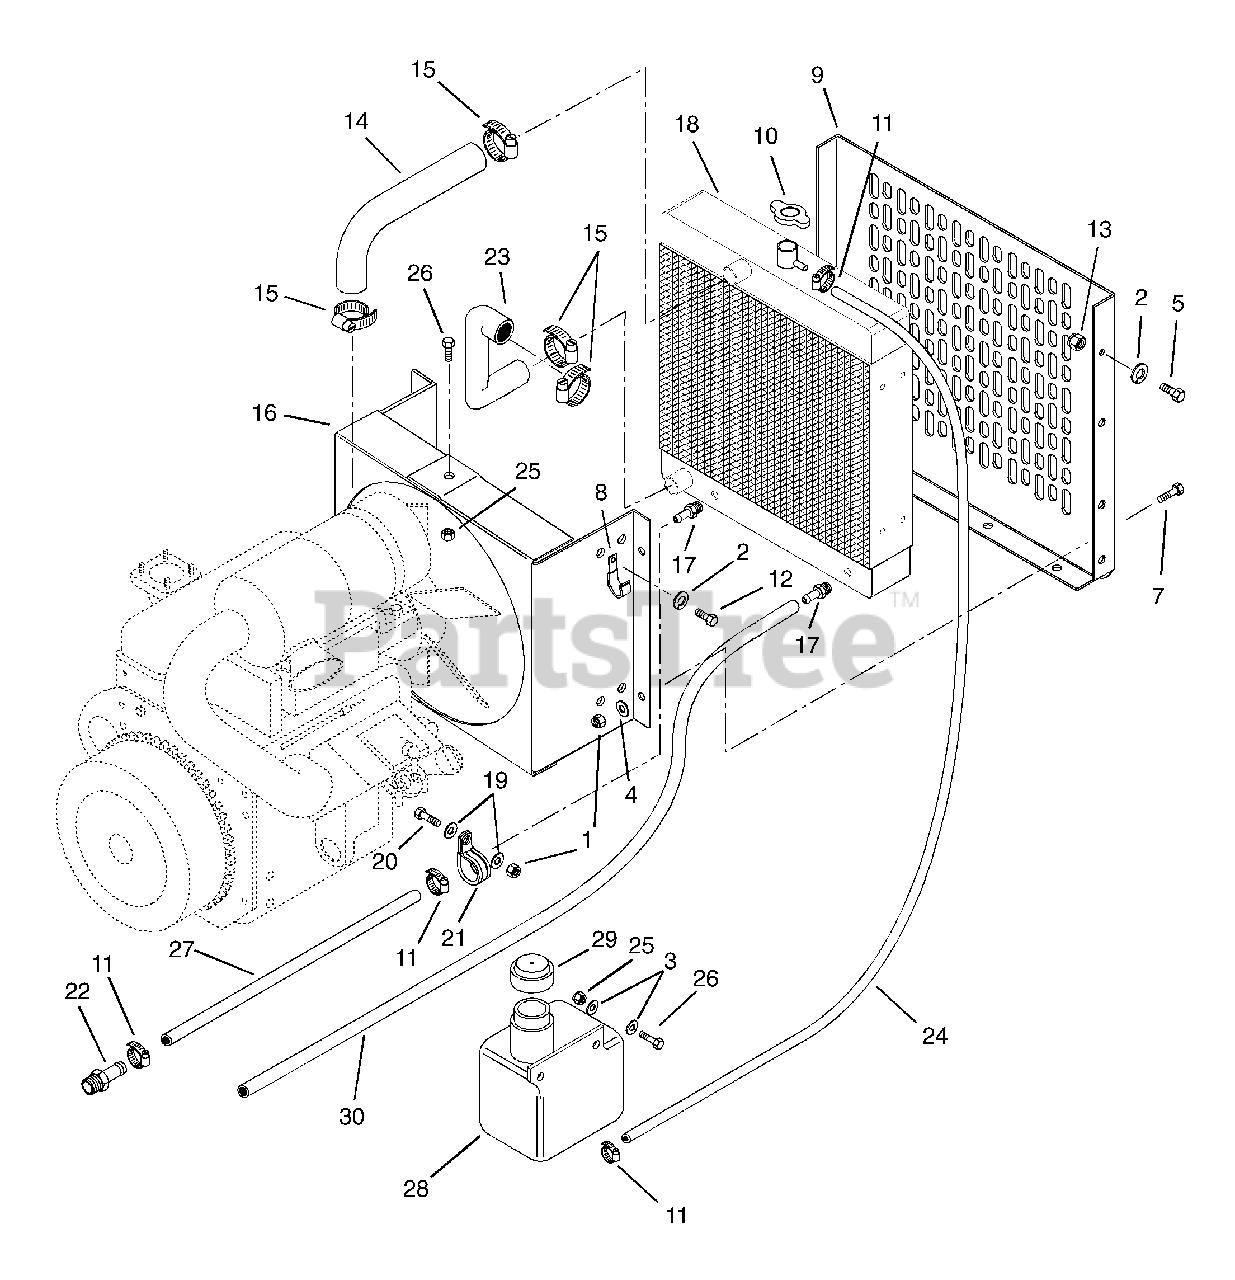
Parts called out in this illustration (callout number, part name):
1	Nut-Locking-Center .38-16
2	Washer-Lock .31 x .078
3	Washer-Flat-Steel .344 x .688 x .065
4	Washer-Flat-Steel .531 x 1.06 x .095
5	Bolt-Hex .50-13 x 1.00 Grade 5
6	Bolt-Hex .50-13 x 1.50 Grade 5
7	Bolt-Hex .38-16 x .75 Grade 5
9	Mount, Radiator
10	Cap, Radiator
11	Hose Clamp
12	Bolt-Hex .31-18 x .50 Grade 5
13	Nut-Locking-Center .50-13
14	Hose, Radiator Upper
15	Clamp-Hose 1.50 x .81 x 1.42
16	Weldment, Fan Cover
17	Adapter .38 Male Pipe to .38 Tube
18	Radiator
19	Washer-Flat-Steel .406 x .812 x .065
20	Bolt-Hex .38-16 x 1.00 Grade 5
21	Clamp, Cushioned Steel
22	Fitting-Adapter .562-18
23	Hose, Lower Radiator
24	Hose, 5/16" ID
25	Nut-Locking-Center .31-18
26	Bolt-Hex .31-18 x .75 Grade 5
27	Hose, 3/8" x 42"
28	Tank, Plastic 1.5 Quart (Coolant)
29	Cap, 1-5/8 Vented
30	Hose, Return 3/8" ID x 52"
